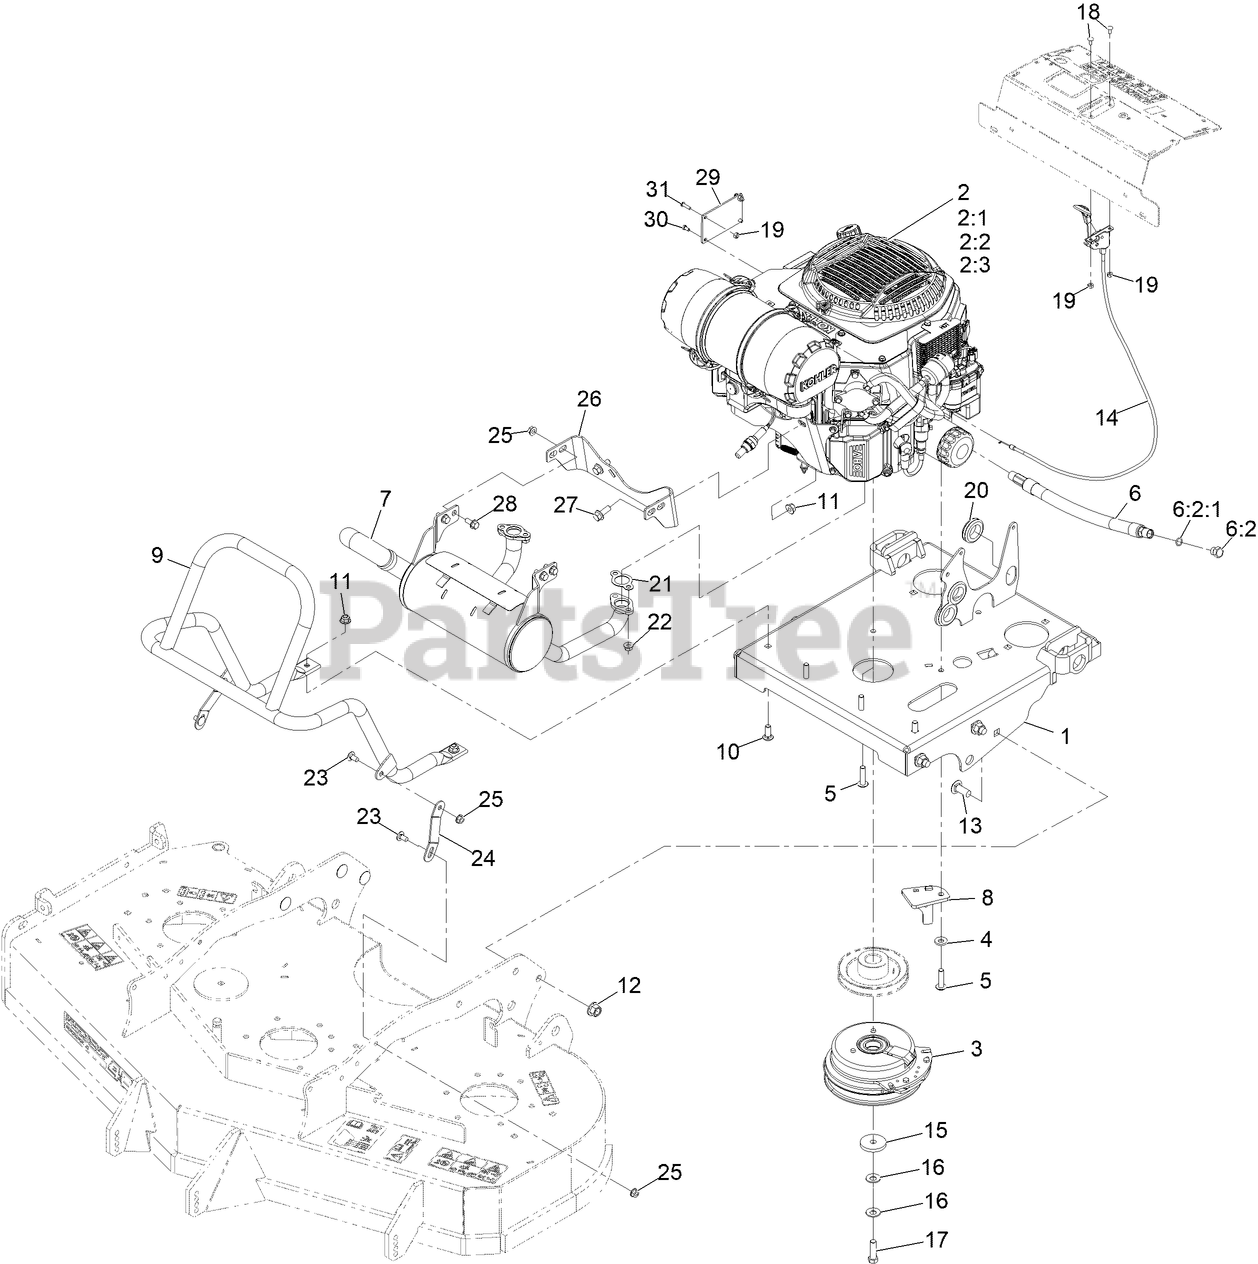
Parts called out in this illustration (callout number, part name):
1	WLD-ENGINE DECK
2:1	Kohler 52 050 02-S Engine Oil Filter
2:2	Kohler 25 083 01-S Engine Air Filter
2:3	Kohler 25 083 04-S Safety Filter
4	WASHER-BELLEVILLE
5	SCREW-BHTF
6	OIL DRAIN HOSE ASM
6:2	PLUG-HH
6:2:1	O-RING
7	MUFFLER- KOHLER, EFI
8	ASM-CLUTCH ANCHOR
9	Tube-Guard Muffler
10	SCREW-CARR
11	NUT-HF, NI
12	Nut-Lock 1/2-13
13	SCREW-CARR, SHORT NECK
14	CONTROL, THROTTLE
15	WASHER-CLUTCH
16	WASHER-SPRING
17	SCREW-HH 7/16-20 X 1 1/2 W/LOCTITE
18	BOLT-CARR
19	NUT-LOCK, NI
20	GROMMET
21	GASKET-EXHAUST
22	NUT-FLANGE
23	SCREW-CARR
24	Strap, Muffler Guard
26	BRACKET-MUFFLER
27	SCREW-HHF 3/8-16 X 1
28	SCREW-HHF
29	Bracket-Ecu
30	Screw-HH
31	Screw-HSBH
